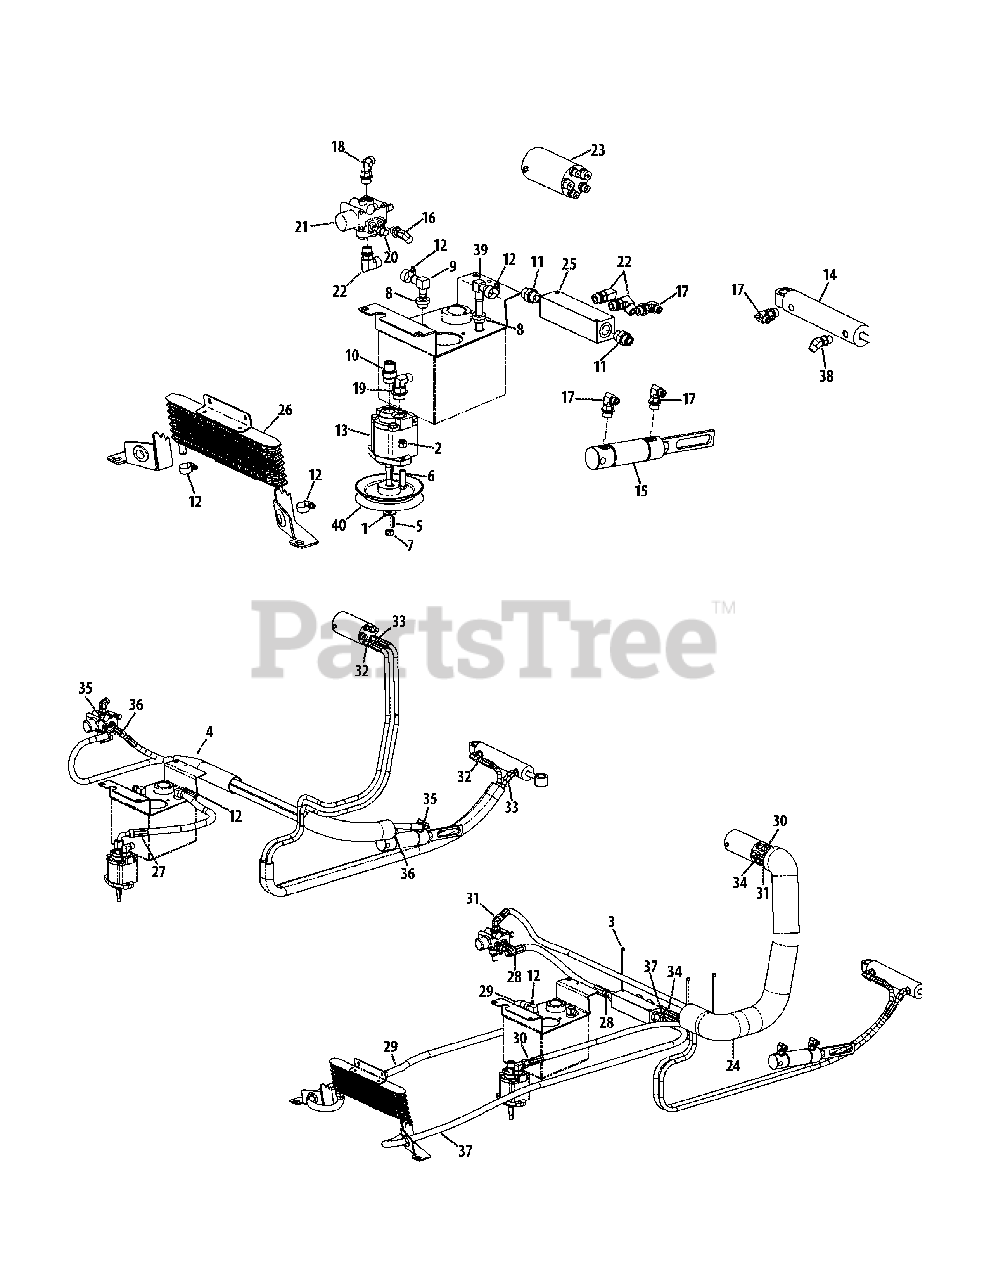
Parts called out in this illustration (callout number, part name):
1	Washer, .438 x 1.00 x .078
2	Nylock Nut, 3/8-16
3	Cable Tie
4	Reel Return Line Sleeve, 1.59
5	Key, .188 x .188 x .875
6	Hex Screw, 3/8-16 x 1.25
7	Counterlock Nut, 3/8-24
8	Grommet, .54 x .78
9	Elbow Fitting, 5/8 x 1/2
10	Hydro Adapter, 8 x 10
11	Hydro Adapter, 8 x 8
12	Hose Clamp
13	Gear Pump, 3.0
14	Steering Cylinder
15	Hydro Cylinder, 1.50 x 2.75
16	Elbow Fitting, 40RB-40RS
17	Elbow Fitting, 40RS-60RB
18	Elbow Fitting, 60RB-60RS
19	Elbow Fitting, 60RS-80RB
20	Fitting, 40RB-40RS
21	Dual Action Lift Hydro Valve
22	Elbow Fitting
23	Hydro Steering Valve
24	Anti-Abrasion Sleeve
25	Hydro Manifold, 8 x 6
26	Oil Radiator
27	Hose Assy. (Tank-Pump)
28	Hose Assy. (Lift Valve-Manifold)
29	Hose Assy. (Exchanger-Tank)
30	Steering Valve Pump Hose Assy.
31	Lift Valve Steering Valve Hose Assy.
32	Steering Ext. Steering Valve Hose Assy.
33	Steering Retractor Steering Valve Hose Assy.
34	Manifold Steering Valve Hose Assy.
35	Cylinder Retractor Lift Valve Hose Assy.
36	Cylinder Extension Lift Valve Hose Assy.
37	Exchanger Manifold Hose Assy.
38	Elbow Fitting
39	Elbow, 1/2 x 5/8
